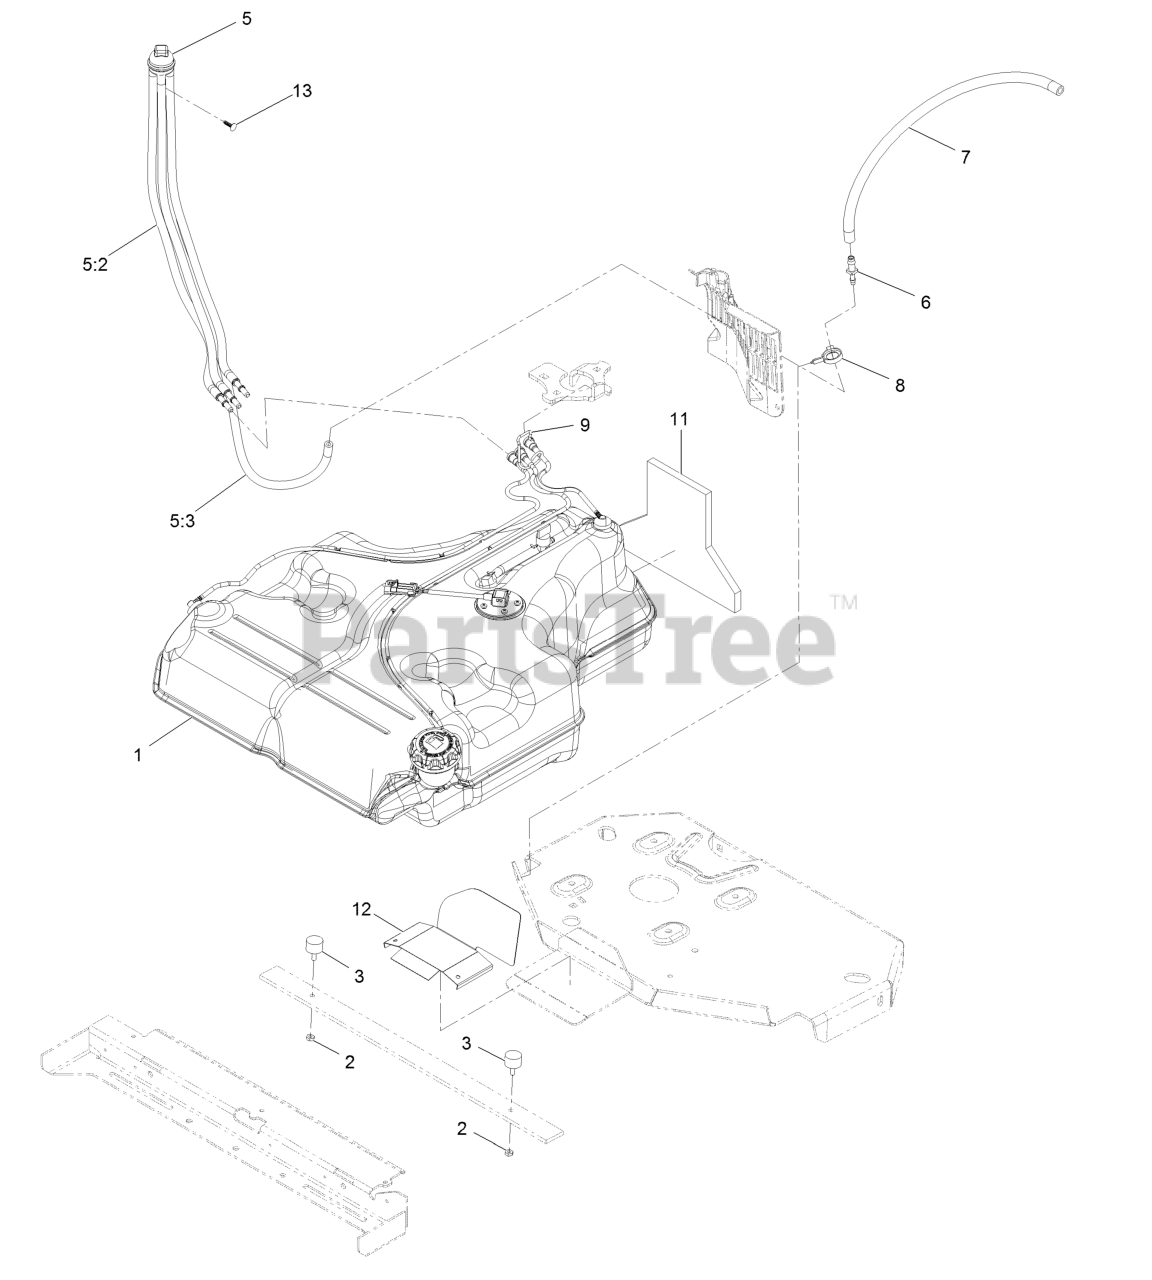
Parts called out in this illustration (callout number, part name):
1	Fuel Tank ASM
2	Nut-Jam 1/4-20
5	Fuel Manifold Vent ASM
5:2	Hose-Fuel Line 24"
5:3	Hose-Fuel
6	Fitting-Straight
7	Hose-Fuel
8	Clamp-Hose
9	Retainer-Line, Vapor
11	Insulation-Foam, Fuel Tank
12	Guard-Exhaust
13	Plug-Plastic
